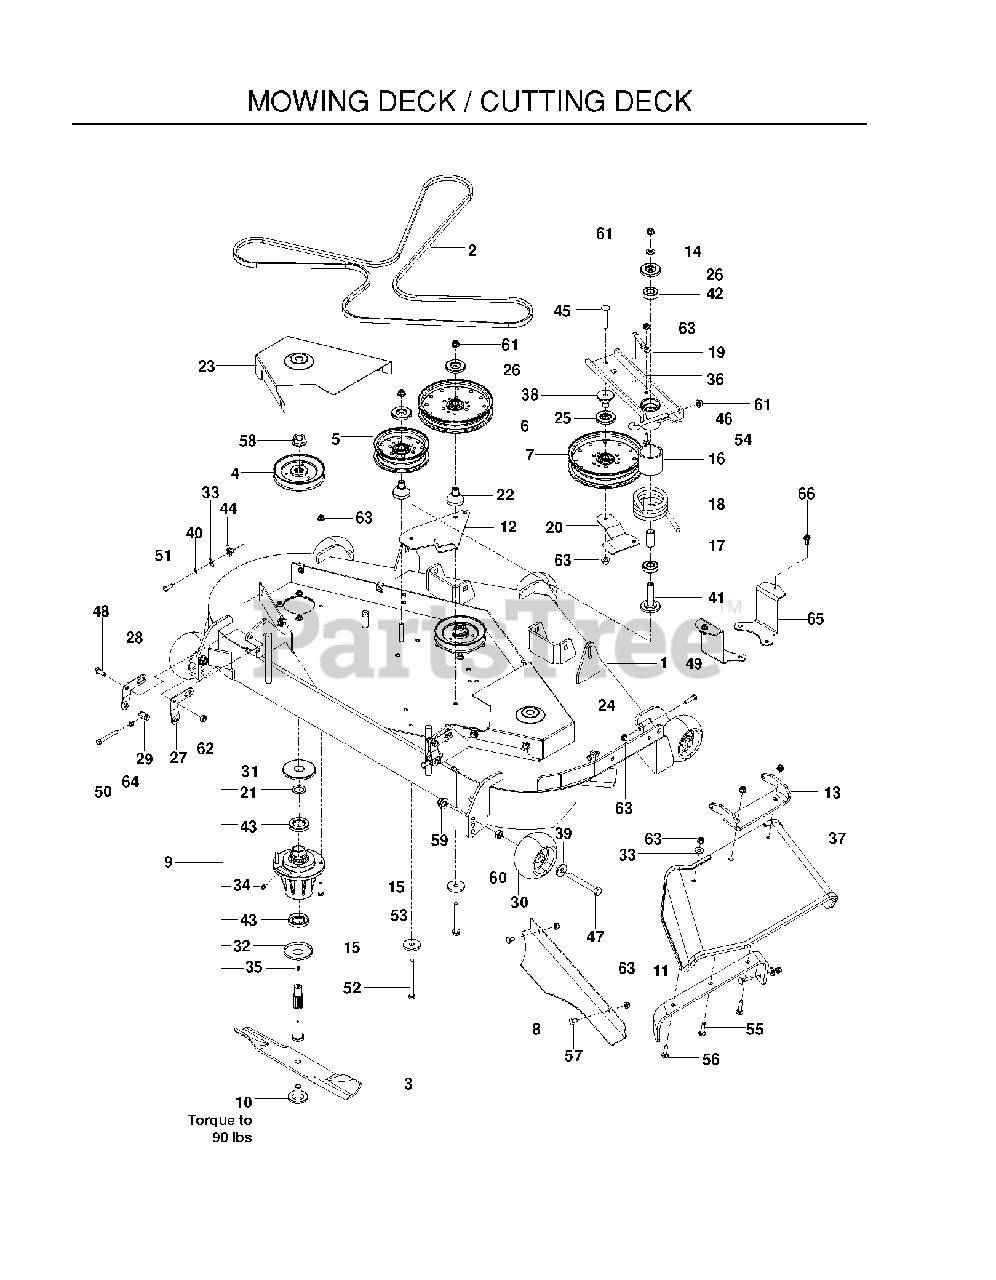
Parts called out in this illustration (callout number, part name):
4	PULLEY 52
5	IDLER PULLEY
6	PULLEY - 7" NARROW
7	PULLEY - IDLER 7"
8	CONFINEMENT PLATE, 52"
10	BLADE BOLT/WASHER
11	BRKT, REINF - CHUTE 52/61"
13	PIVOT BRACKET - CHUTE
14	WASHER, 3/8 THICK
15	SPINDLE WASHER
16	SPACER, IDLER PIVOT
17	SPACER, IDLER BEARINGS
18	SPRING, TORSION, IDLER
19	BELT KEEPER
20	BELT GUIDE, BLK
21	MACHINE BUSHING
23	BELTSHIELD - L.H. BLUE
24	BELTSHIELD - R.H. BLUE
25	SHIELD, DUST
26	DUST SHIELD
27	PITCH, ADJUST, LT
28	PITCH, ADJUST, RT
29	TRUNION, PITCH
31	TOP DUST CAP
32	BOTTOM DUST CAP
33	WASHER 5/16 FLAT
34	PLUG-VENTED
37	CHUTE, RUBBER DISCHARGE 52/61"
38	BEARING, IDLER ARM
39	WASH USS FLAT 1/2
40	WASH 5/16 DISC SPRING ZD
41	BEARING, IDLER PIVOT
42	BEARING, BALL
43	SHAFT SEAL
44	U-CLIP 5/16-18 NUT RETAINER
45	CARRIAGE BOLT 3/8-16 X
46	EYE BOLT, 3/8 X 4"
47	HCS 1/2-13 X 4 GR 5 ZD
48	HCS 3/8C X 1
49	HCS 5/16C X 1 1/4
50	HCS 5/16-18 X 2 1/2 TPBLT
51	HCS 5/16C X 3/4
52	HCS 3/8-16 X 4-1/2 GR 8 ZD
54	RHSSNB 5/16C X 1.0
55	RHSNB 5/16-18 X 1-1/2 GR 5 ZD
56	BOLT, CARRIAGE 5/16X1-1/4
57	CARRIAGE BOLT 5/16C X 5/8"
58	NUT FLANGE 3/4-16
59	NUT, 1/2-13 HEX FLG NYLOC ZD
60	NUT 1/2 HEX JAM
61	NUT 3/8-16 HEX FLG NYLOC ZD
62	NUT 3/8-16 NYLOC
63	5/16-18 NYLOC FLANGE NUT
64	NUT 5/16C HEX
66	SCREW- 1/4-20 X 5/8
